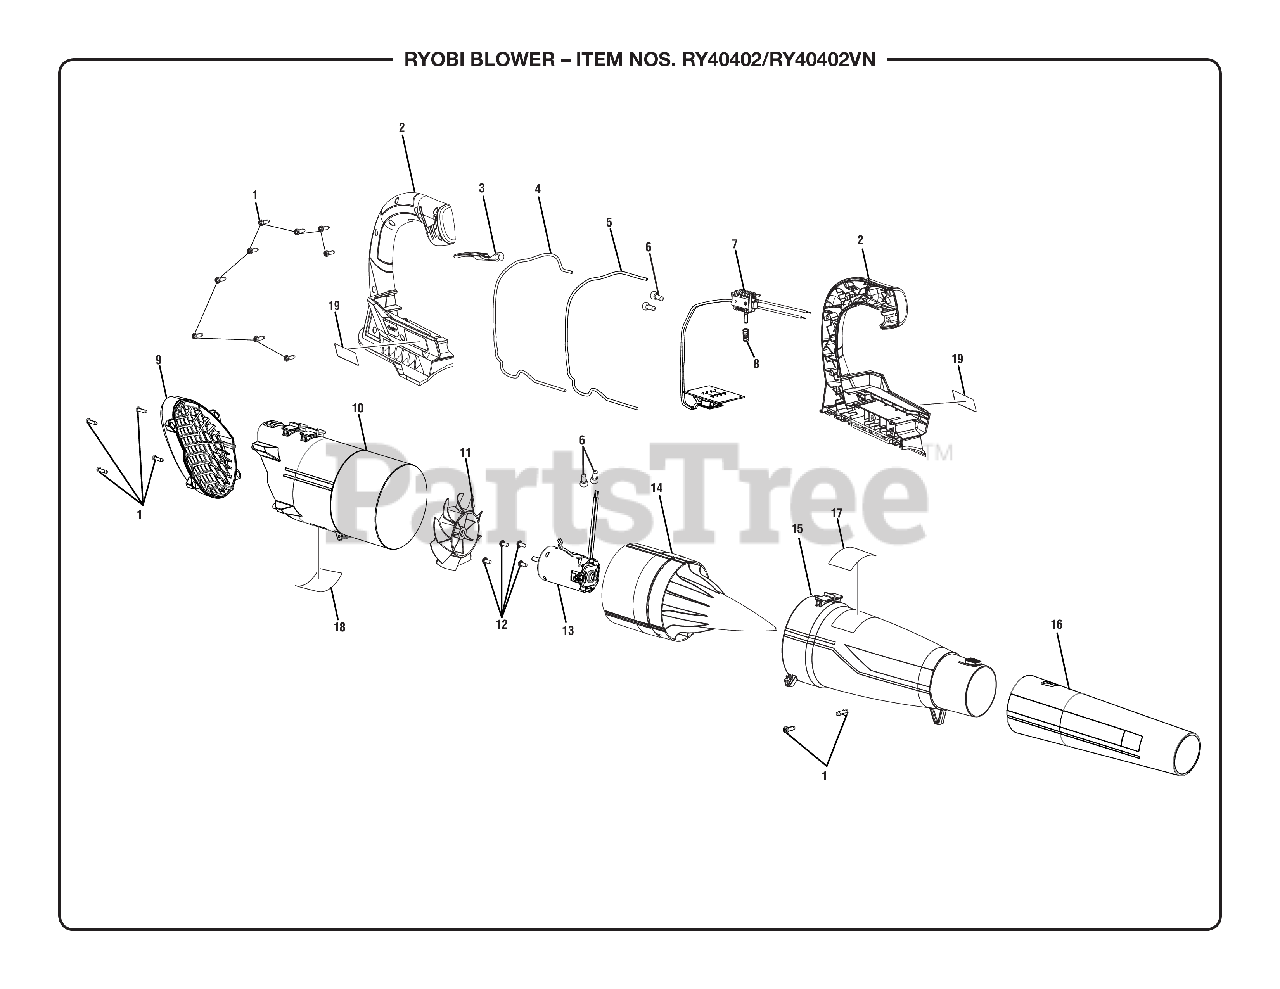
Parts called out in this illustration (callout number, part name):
1	Screw (M4 x 14 mm, T15 Torx Pan Hd.))
2	Handle Assembly
3	Trigger Assembly (Variable Speed)
4	Lead Wire (Red)
5	Lead Wire (Black)
6	Wire Connector (Closed End)
7	Switch Assembly
8	Compression Spring (Trigger)
9	Inlet Housing Cover
10	Inlet Housing
12	Screw w/Lock Washer (M5 x 8 mm, Pan Hd.)
14	Housing Assembly
15	Blower Housing Outlet
16	Blower Tube
17	Icon Warning Label
18	Data Label
19	Logo Label (Left/Right)
